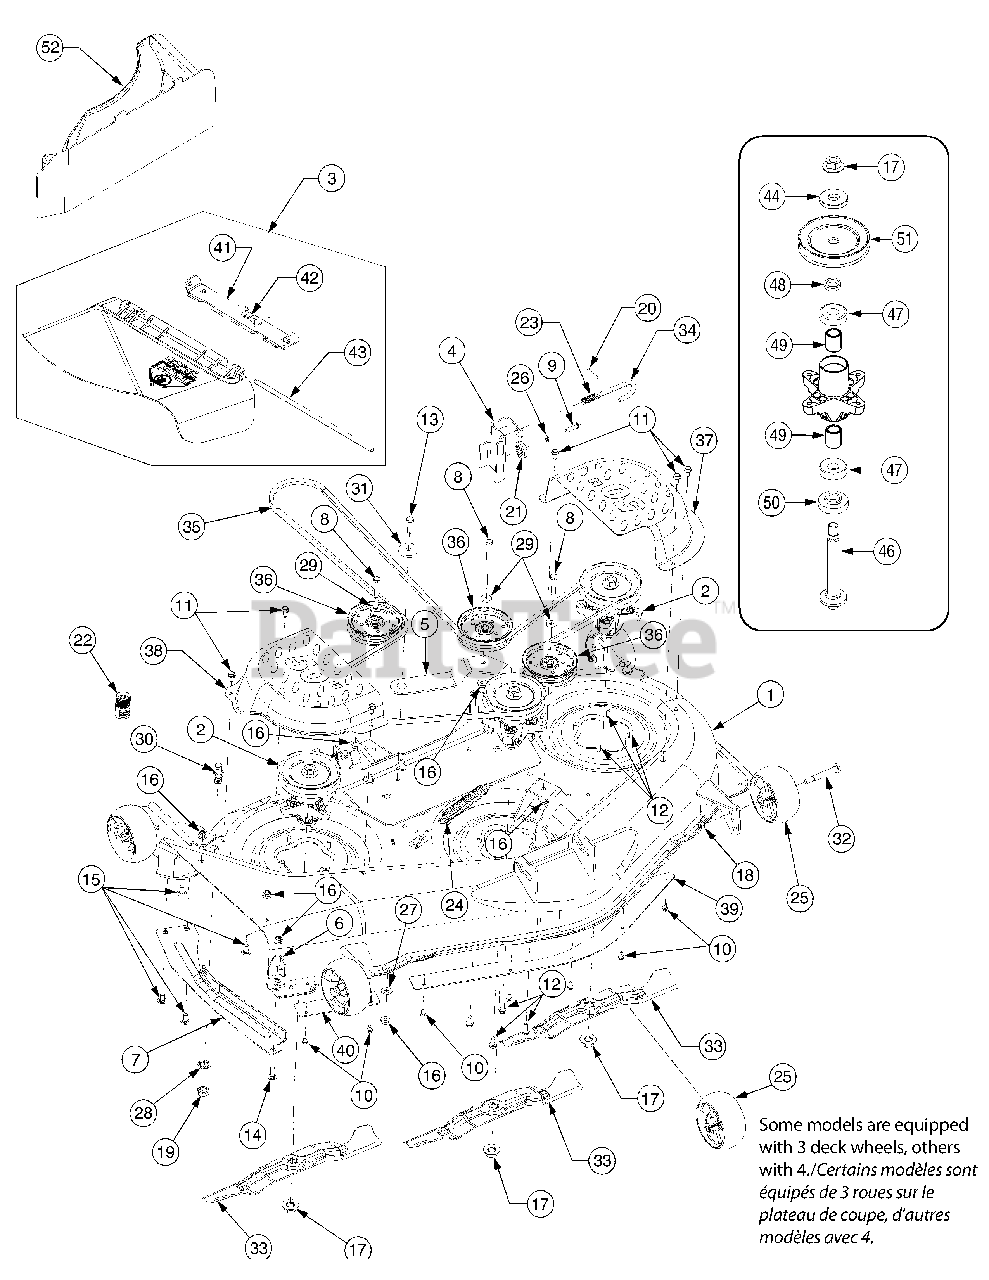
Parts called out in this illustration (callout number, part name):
1	Deck Housing
2	Spindle Assembly
3	Discharge Chute Ass’y
4	Deck Adjustment Brack w/Weld Nut
5	Idler Arm
6	Chute Stop Deflector
7	Guard, Finger
8	Hex Screw 3/8-16 x 1.75
9	Hex Bolt 5/16-18 x 1.25
10	Hex Wash S-Tapp Scr 1/4-20 x .50
11	Hex Wash HD AB Scr 5/16-12 x .75
12	Hex Wash. Hd. Scr. 5/16-18 x .75 Lg.
13	Hex Bolt 3/8-16 x 1.25
14	Carriage Bolt 3/8-16 x 1" Lg. (Gr. 5)
15	Short Neck Carriage Bolt 3/8-16 x .75
16	Flange Lock-Nut 3/8-16 Gr. F Nylon
17	Hex Flange Nut 5/8-18
18	Hex. Flanged L-Nut 3/8-16 Gr. F
19	Hex Nut M16-1.5 DIN 936
20	Cotter Pin 1/8" Dia x 1.25
21	Deck Adjustment Gear
22	Water Nozzle Adaptor
23	Comp. Spring .531 OD x 1.75 Lg.
24	Extension Spring .94 OD x 6.74
25	Deck Wheel 5.0
26	L-Wash 5/16 ID
27	Cupped Washer .45 x 1.0 x .062
28	L-Washer Internal
29	Flat Washer .38 x .93 x .11
31	Shoulder Spacer .884 x .190
32	Shoulder Screw, 1/2 Diameter x 2.5
33	Blade 17.9" Lg.
34	Deck Release Pin
35	V-Belt Type A Sec x 134
36	Idler Pulley w/Flange 4.25 Dia
37	LH Belt Cover
38	RH Belt Cover
39	Deck Skirt Center
41	Chute Mounting Bracket
42	Tortion Spring
44	Flat Washer .76 ID x 1.5 OD x .12
45	Grease Fitting
46	Spindle Shaft 5.75 Lg.
47	Ball Bearing 20 x 47 x 14:6204:DS
48	Spacer .79 x 1.25 x .175
49	Spacer .080 x 1.10 x 1.322" Lg.
50	Spacer .79 x 1.82 x .55
51	V-Type Pulley, 5.29
52	Mulching Plug
